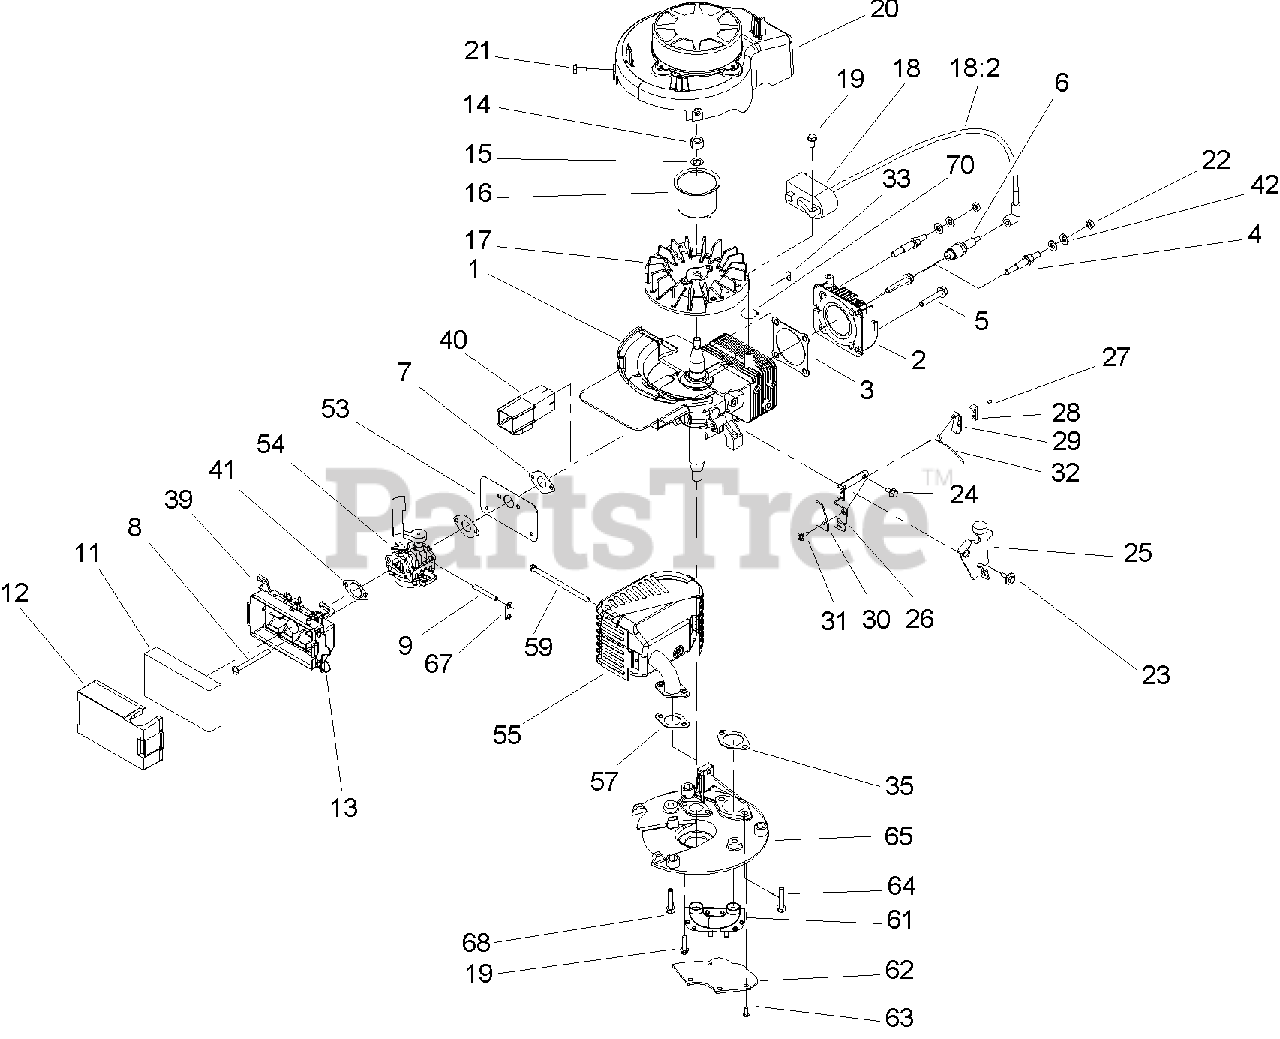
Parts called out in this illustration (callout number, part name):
1	SHORT BLOCK ASM
2	HEAD-CYLINDER
3	GASKET-HEAD
5	SCREW-HWH
6	SPARK PLUG
7	GASKET-INTAKE
9	HOSE-PRIMER
11	FILTER-AIR
12	COVER-FILTER, AIR
13	RETAINER-COVER, FILTER
15	WASHER-LOCK
16	CUP-STARTER
17	FLYWHEEL
18	MODULE-IGNITION
18:2	LEAD-TENSION, HIGH
20	SHROUD-RECOIL
21	SCREW-HH
23	SCREW-SHOULDER
24	SCREW-HWH
25	PLATE-BRAKE
26	PLATE-BRAKE
27	RIVET-PLASTIC
28	STRAP-INSULATION
29	STRAP-GROUND
30	STOP-STRAP, GROUND
32	LEAD WIRE-SWITCH, BRAKE
35	GASKET-EXHAUST
39	AIR BASE ASM
40	TUNNEL-INLET
41	GASKET-FILTER
42	WASHER-BELLEVILLE
53	SHIELD-CARB
54	CARBURETOR ASM
55	MUFFLER AND GUARD
59	BOLT-CONSOLE
61	PIPE-TRANSFER
62	COVER-MUFFLER
63	SCREW-HHF
64	SCREW-HH
65	PLATE-MOUNTING
67	HOSE-RETAINER
70	STRAP-TIE
